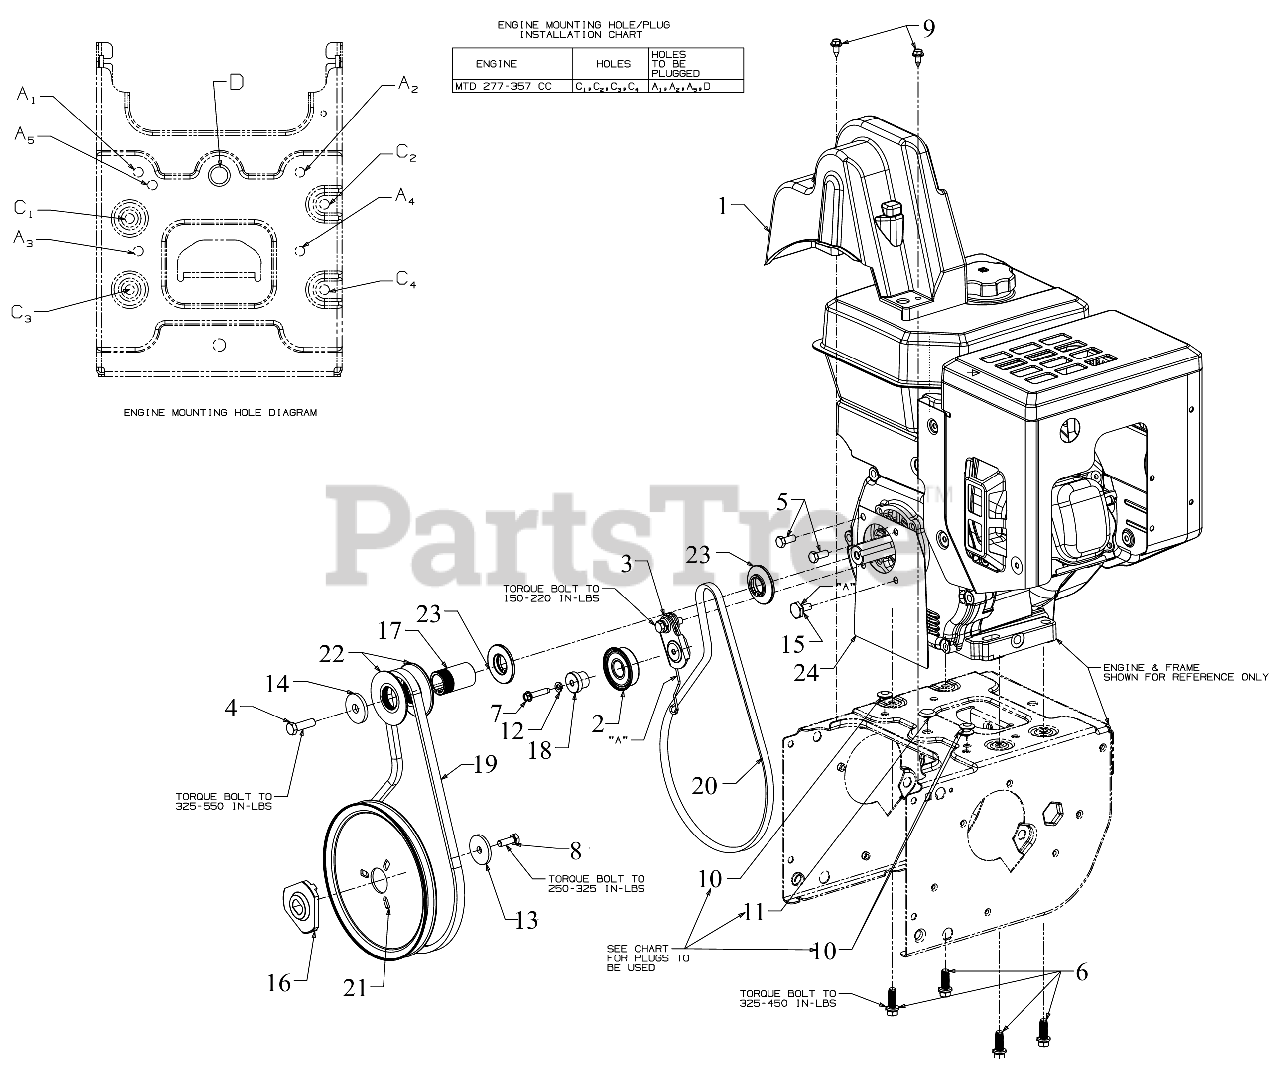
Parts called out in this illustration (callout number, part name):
1	BELT COVER (LARGE BLOCK)
2	IDLER PULLEY ASSEMBLY
3	SCREW 5/16-24 x 1.25 GR5
4	SCREW 3/8-24X1.25
5	SCREW 5/16-24 x .750 GR5
6	SCREW 3/8-16 x 1
7	SCREW 1/4-20 x 1.25
8	SCREW 5/16-24 x .875 GR5
9	SCREW 1/4-20X.625
10	PLUG-3/8 DIA ID x 3/32
11	PLUG-1/2 ID x 3/32
12	LOCK WASHER
13	FLAT WASHER
14	FLAT WASHER .45 x 1.5 x .172 HT
15	SHOULDER SCREW
16	ADAPTER PULLEY .75 DIA W/DD
17	PULLEY SPACER
18	SHOULDER SPACER
19	BELT-.500 x 37
19	Cub Cadet AUGER BELT
19	Genuine Factory Parts AUGER BELT
20	V-BELT 3/8 x 35.68"
20	Cub Cadet DRIVE BELT
20	DRIVE BELT (04201A)
21	AUGER PULLEY
22	HALF PULLEY 4L V x 2.6 OD
23	HALF PULLEY-3/8 V x 1.7160
24	ENGINE PLATE (FRONT COVER)
